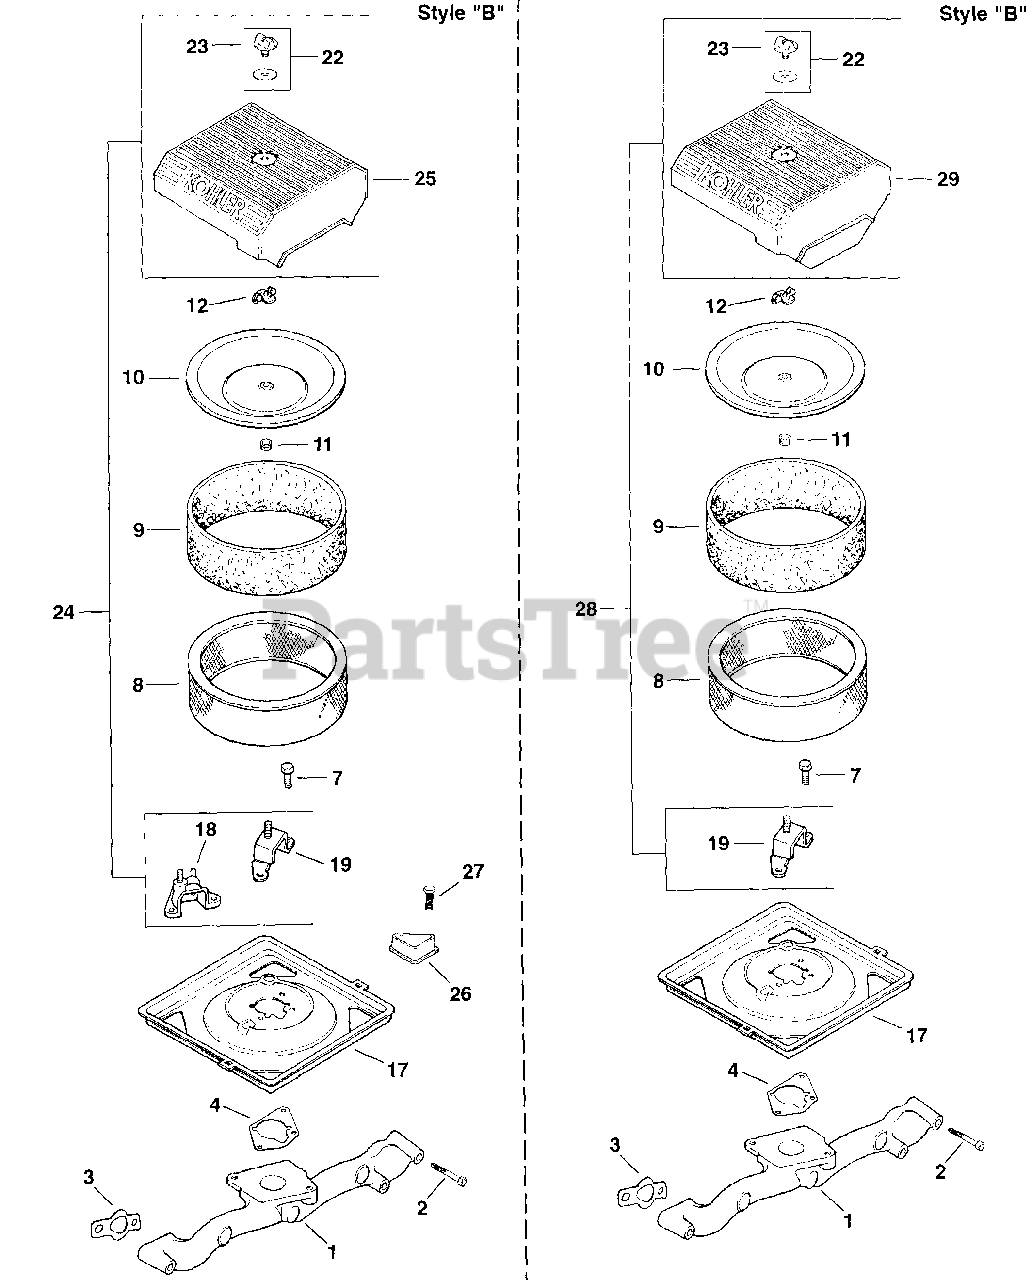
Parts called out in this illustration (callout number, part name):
1	MANIFOLD, METAL INTAKE
2	Screw, hex. flange M6x1.0x55
3	GASKET, INTAKE MANIFOLD USE 24 041 79-S
4	GASKET, AIR CLEANER BASE
7	SCREW - USE M-639016
8	ELEMENT, AIR CLEANER - Also available Retail Packaged 47 883 03-S1 Air Filter Kit
9	ELEMENT, PRECLEANER (LOW)
10	COVER, INNER AIR CLEANER
11	SEAL, INNER AIR CLEANER
12	NUT, WING
18	KIT - USE 24 755 86
19	BRACKET,AIR CLEANERBASE-USE 24 126 206-S
22	KIT - USE 54 755 01
24	KIT, AIR CLEANER COVER
25	COVER, AIR CLEANER
